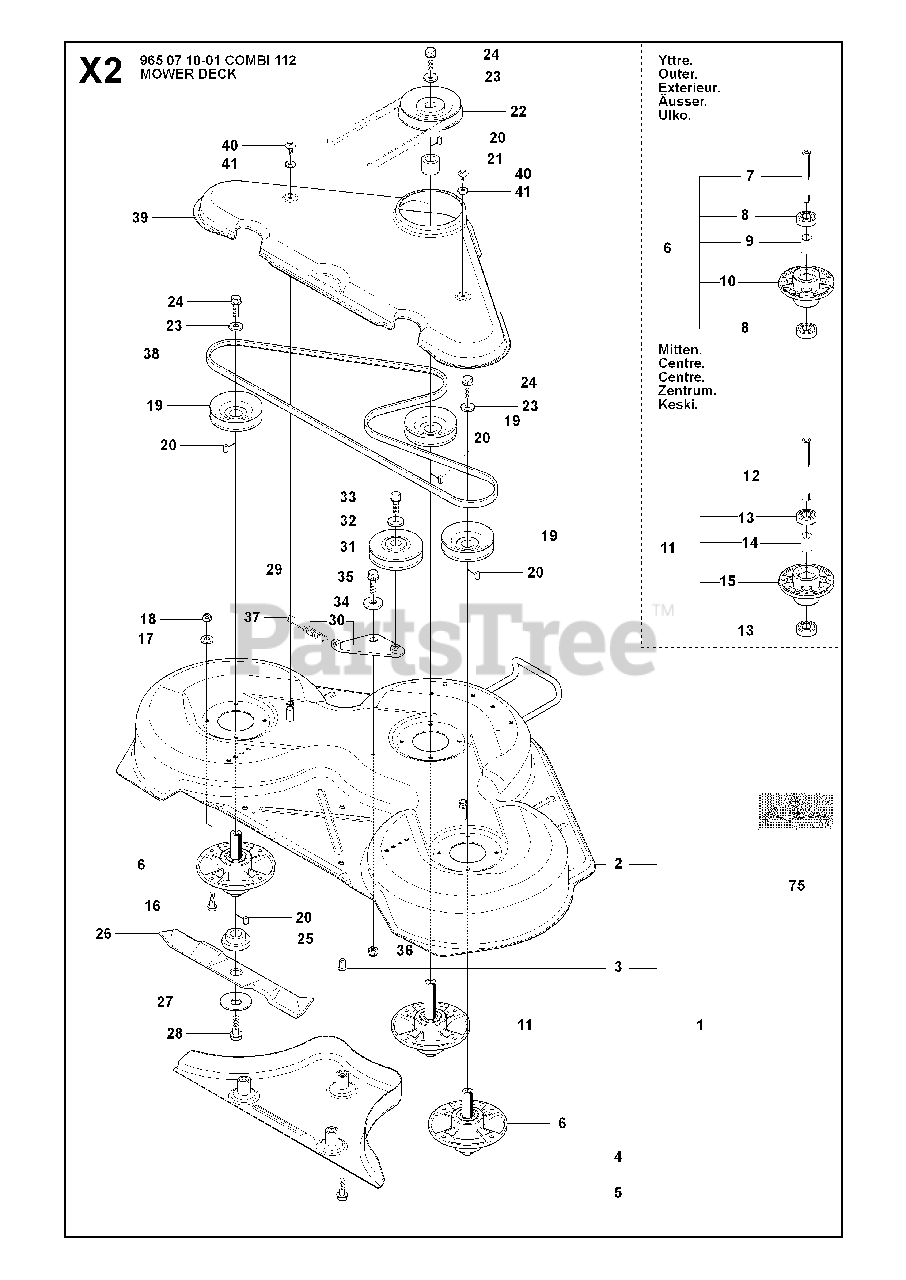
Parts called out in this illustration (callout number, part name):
6	RP SPINDLE ASSY
10	BEARING HOUSING
11	RP SPINDLE ASSY
15	BEARING HOUSING
17	WASHER BRB 8.4X17
18	LOCKNUT M8
26	BLADE
29	BELT TENSIONER ASSY
30	BELT TENSIONING ARM
34	WASHER
36	LOCKNUT M8
38	BELT
